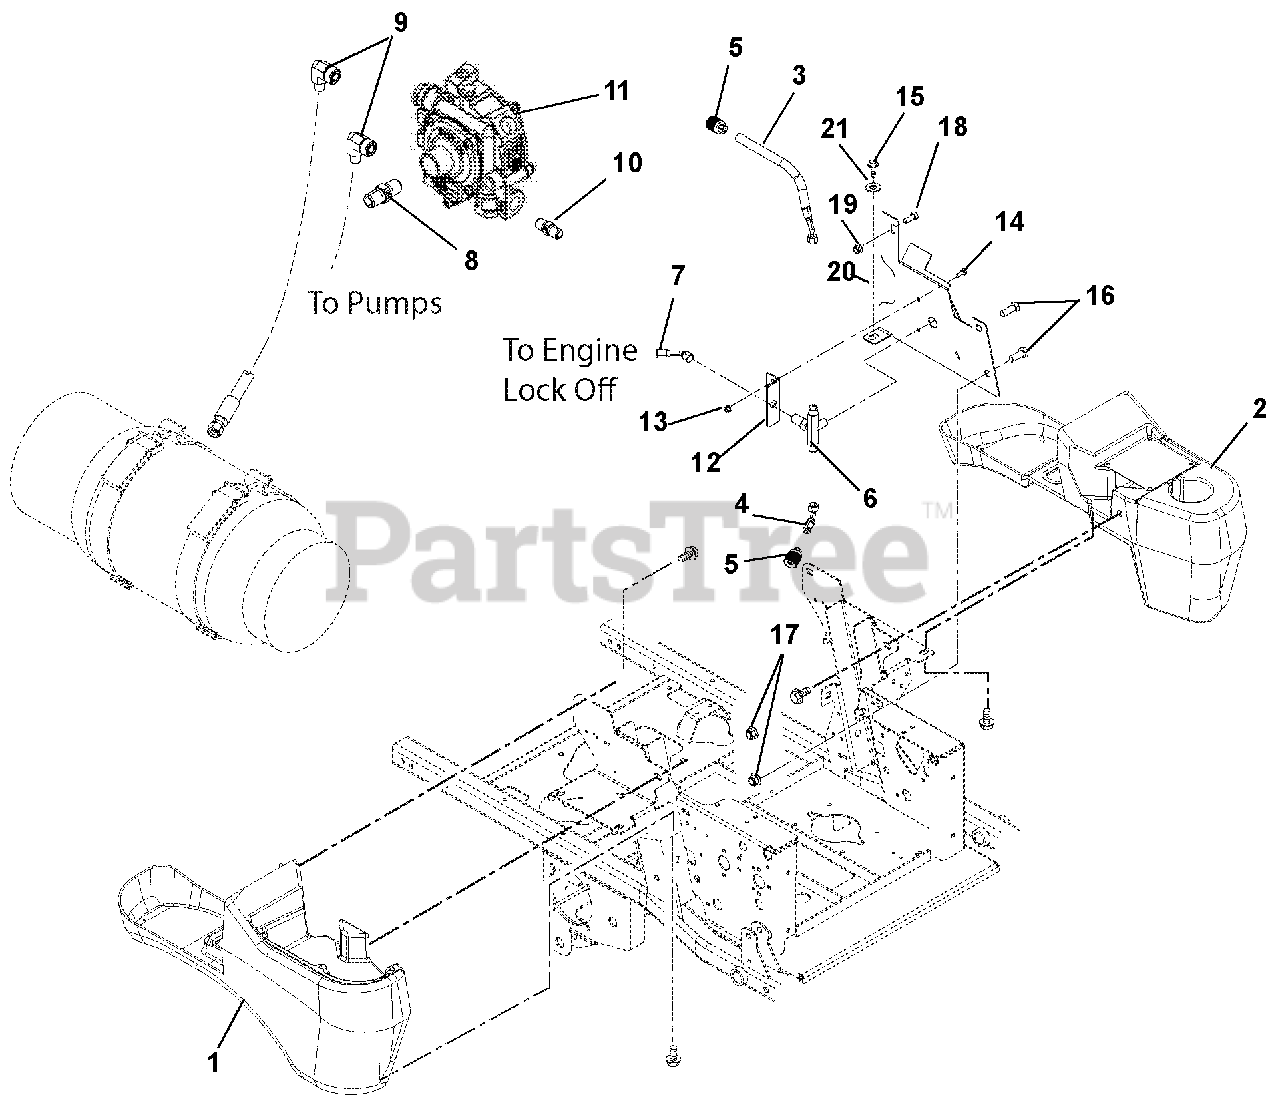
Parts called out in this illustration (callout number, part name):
1	Fender, Right Hand 200 Series LPG
2	Fender, Left Hand 200 Series LPG
3	Hose, LPG
4	Hose, LPG
5	Fitting, LPG Tank
6	Valve, Sherwood T
7	Hose, LPG
8	Fitting, Barb .50-.38
9	Fitting, Barb 1/4NPT x 8ORF 90 Degree
10	Fitting, LPG Straight 1/4NPT Parker 216P-4
11	Regulator, LPG IMPCO T60
12	Mount, Fuel T
13	Nut, Locking Top Flange .31-18
14	Bolt, Hex .31-18 x .75 Grade 5
15	Weldment, Support Fuel T
16	Bolt, Hex .50-13 x 1.25 Grade 5
17	Nut, Locking Top Flange .50-13
18	Bolt, Hex .38-16 x 1.50 Grade 5
19	Nut, .38-16 Nyloc Flange
20	Screw, Tapping .38-16 x 1.00 Hex Washer Head
21	Washer, Flat Steel .438 x 1.00 x .083
